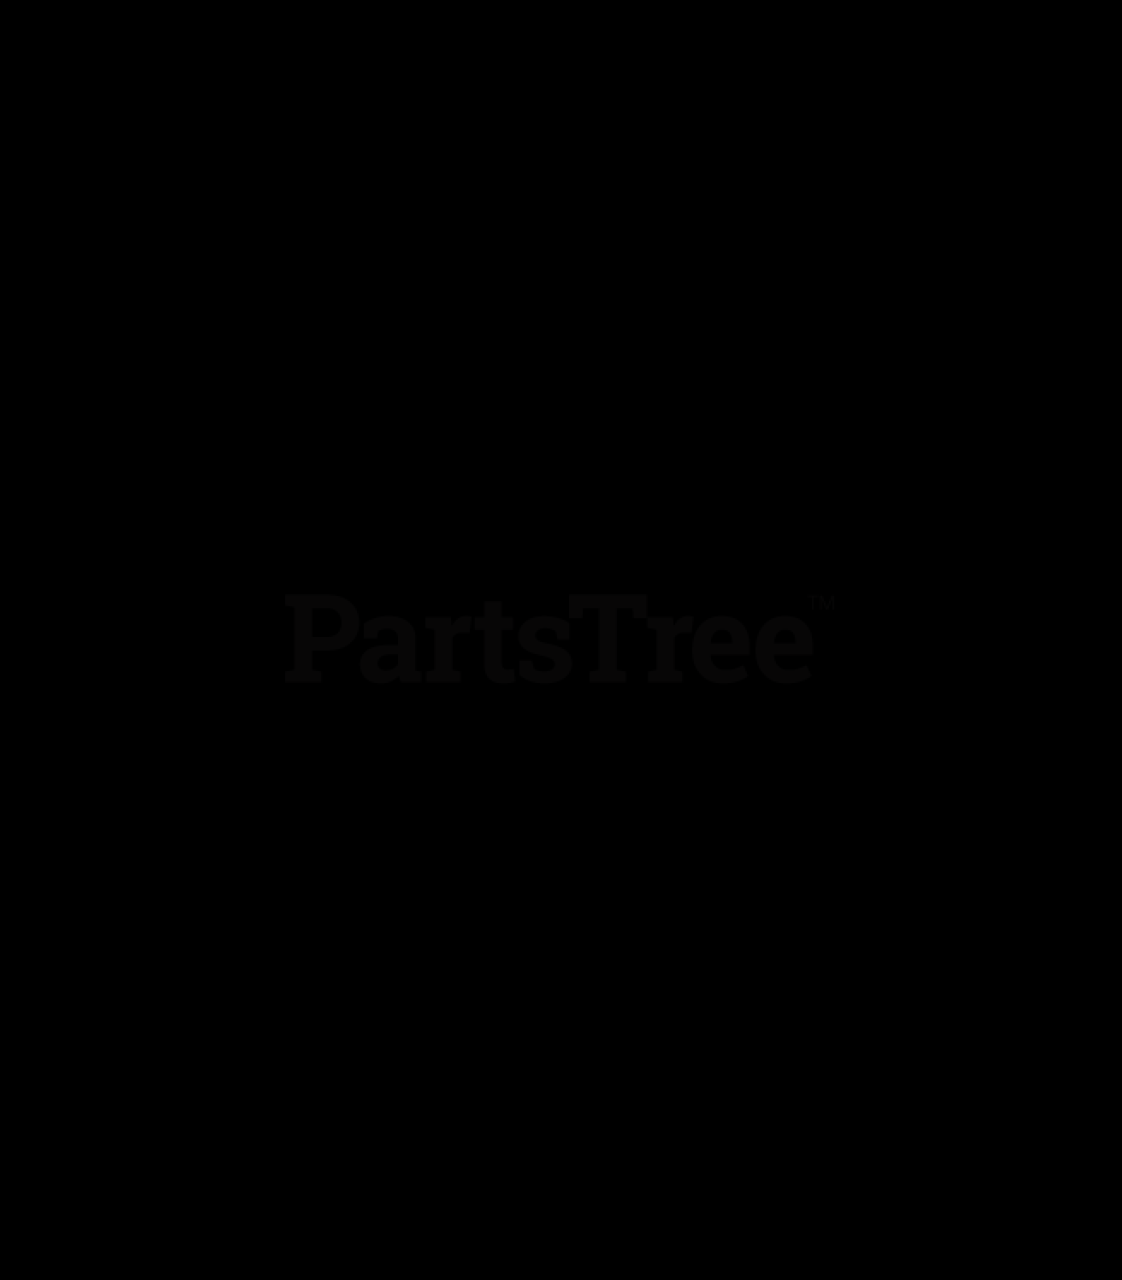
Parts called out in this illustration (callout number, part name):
1	Weldment, Frame
2	Weldment, Front Axle
3	Bushing, Flange 1.25 x 1.50 x 1.00 x .200
4	Fitting, Lube 45 Degree GM411031
5	Pin, Axle
7	Nut, Locking Nylon 1.0-14
8	Screw, Tapping .38-16 x .75
9	Axle Cover
10	Button, Bumper
11	Bolt, Hex .50-20 x 1.00 Grade 5
12	Panel, Inspection
13	Step, Ingress
14	Bolt, Round Head Square Neck .31-18 x 1.75 Grade 5
15	Nut, Locking Top Flange .31-18
16	Plate, Kick
17	Channel, Cross
18	Pulley, Idler
19	Nut, Retainer .375-16 x .37
20	Bolt, Serrated Flange Washer Head .38-16 x 1.00
21	Bolt, Hex .50-13 x 3.25 Grade 5
22	Bolt, Hex .50-13 x 2.25 Grade 5
23	Washer, Flat Steel .505 x .88 x .072
25	Nut, Spin Lock Flange .312-18
26	Washer, Flat Steel .064 x 1.810 x .250
27	Bolt, Hex .31-18 x 1.00 Grade 5
28	Washer, Flat Steel .344 x 1.125 x .135
29	Nut, Locking Top Flange .50-13
30	Cable, Seat Prop
31	Guard, Grass
32	Bracket, Weight
33	Weight, Cast Iron
34	Bolt, Hex .50-13 x 1.25 Grade 5
35	Nut, Locking Top Flange .50-13
36	Bolt, Hex .50-13 x 4.50 Grade 5
37	Washer, Flat Steel .531 x 1.06 x .095
38	Nut, Spin Lock, Flange .312-18
39	Weldment, Right Hand Axle Cover Support
40	Weldment, Left Hand Axle Cover Support
41	Bolt, Hex .38-16X3.00 Grade 5
42	Nut, Locking-Top-Flange .38-16
43	Plate, Backer
44	Spacer, 1.25OD x 1.0ID x 3.63
